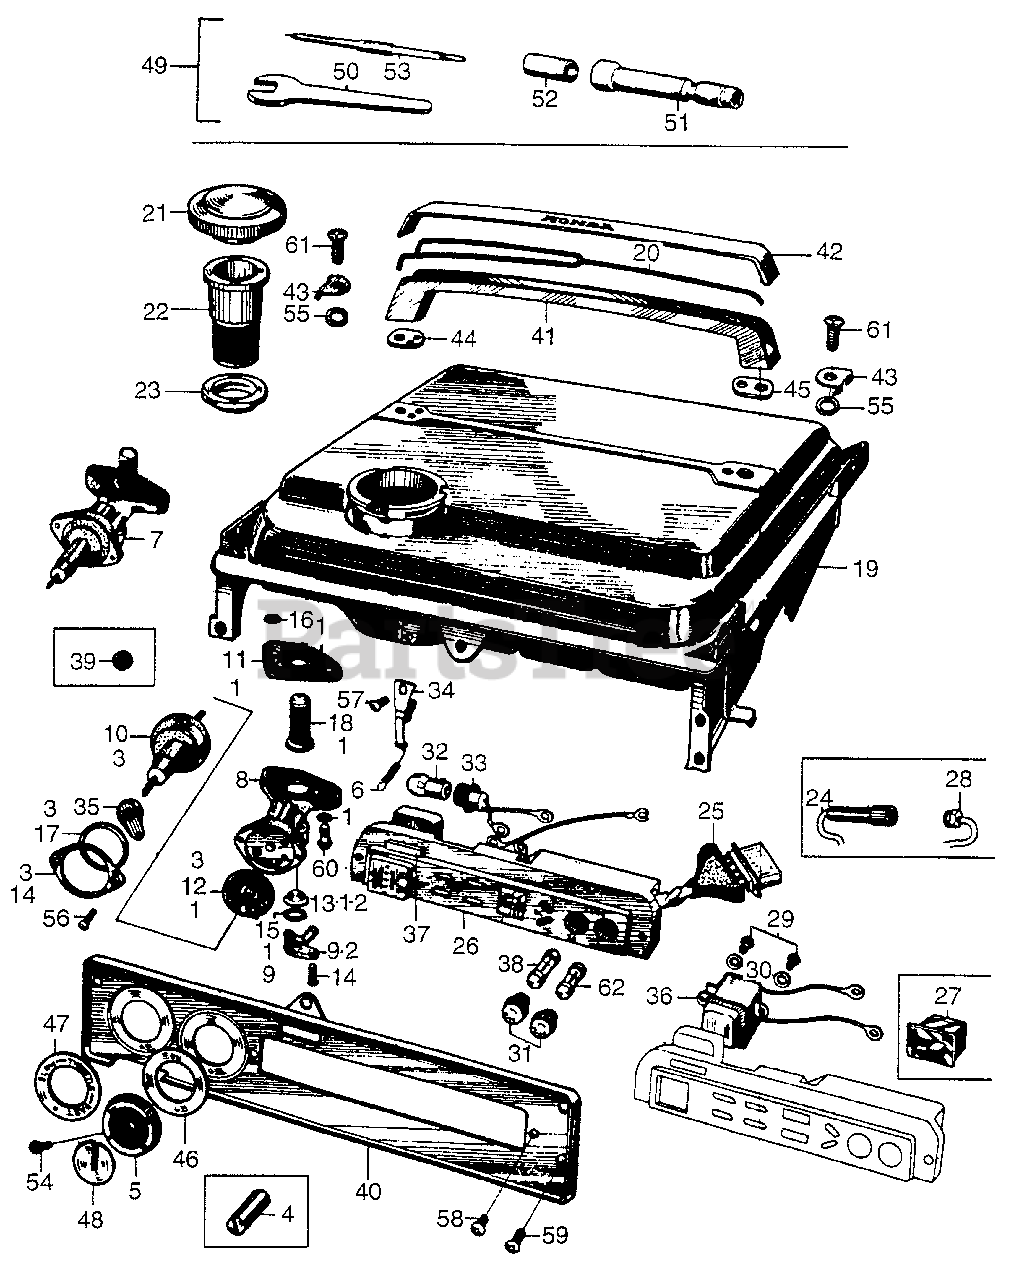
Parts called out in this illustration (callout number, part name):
4	NUT, KNOB (NOT AVAILABLE)
5	KNOB, CONTROL (NOT AVAILABLE)
5	KNOB, CONTROL
6	GASKET, STRAINER SETTING (NOT AVAILABLE)
7	PETCOCK ASSY. (NOT AVAILABLE)
7	PETCOCK ASSY.
8	BODY, FUEL LEVER (NOT AVAILABLE)
9	CAP, PETCOCK (NOT AVAILABLE)
10	LEVER, VALVE (NOT AVAILABLE)
11	GASKET A, PETCOCK (NOT AVAILABLE)
12	GASKET, VALVE
13	FILTER, CHECK (NOT AVAILABLE)
14	PLATE, LEVER
15	GASKET, O-TYPE (NOT AVAILABLE)
16	COLLAR, LEVER GASKET
17	SPRING, PETCOCK LEVER (NOT AVAILABLE)
18	FILTER, CHECK (NOT AVAILABLE)
19	TANK, FUEL
20	TUBE, HANDLE BREATHER (NOT AVAILABLE)
21	CAP, TANK (NOT AVAILABLE)
22	FILTER, FUEL
23	RUBBER, FILTER (NOT AVAILABLE)
24	CONNECTOR A, FUSE (NOT AVAILABLE)
24	CONNECTOR A, FUSE (RED)
26	RECEPTACLE ASSY., SWITCH
26	RECEPTACLE ASSY., SWITCH (NOT AVAILABLE)
27	SWITCH ASSY., CHANGE
27	SWITCH ASSY., CHANGE (NOT AVAILABLE)
28	CONNECTOR B, FUSE (RED)
28	CONNECTOR B, FUSE (WHITE)
29	SCREW, PAN (2X4)
32	BULB, DASH (NOT AVAILABLE)
32	BULB, DASH (6V3W) (STANLEY)
33	SOCKET ASSY.
34	SWITCH ASSY., ENGINE (NOT AVAILABLE)
35	ARM, SWITCH (NOT AVAILABLE)
36	METER, CYCLE
36	METER, FREQUENCY
38	FUSE (3A)
38	FUSE ASSY., SPARE
39	RUBBER, GUIDE (NOT AVAILABLE)
40	PANEL, FR. (NOT AVAILABLE)
40	PANEL, FR.
41	HANDLE, CARRY
42	COVER, HANDLE (NOT AVAILABLE)
43	HOOK, HANDLE COVER
44	GASKET A, HANDLE (NOT AVAILABLE)
45	GASKET B, HANDLE (NOT AVAILABLE)
46	MARK, VALVE KNOB (NOT AVAILABLE)
47	MARK, THROTTLE KNOB
48	MARK, CONTROL KNOB
49	TOOL ASSY. (N/A: SEE COMPONENTS)
50	WRENCH (9MM) (OPEN END)
51	WRENCH, SPARK PLUG (NOT AVAILABLE)
52	RUBBER, FRICTION (NOT AVAILABLE)
53	SCREWDRIVER
54	SCREW, STOP (3MM)
55	O-RING (5X1.5) (NOT AVAILABLE)
56	SCREW, PAN (3X6) (NOT AVAILABLE)
57	SCREW, PAN (3X6) (NOT AVAILABLE)
58	SCREW, PAN (4X8)
59	SCREW, PAN (5X8)
60	SCREW, PAN (6X16)
61	SCREW, PAN (6X20)
62	FUSE A (7A)
